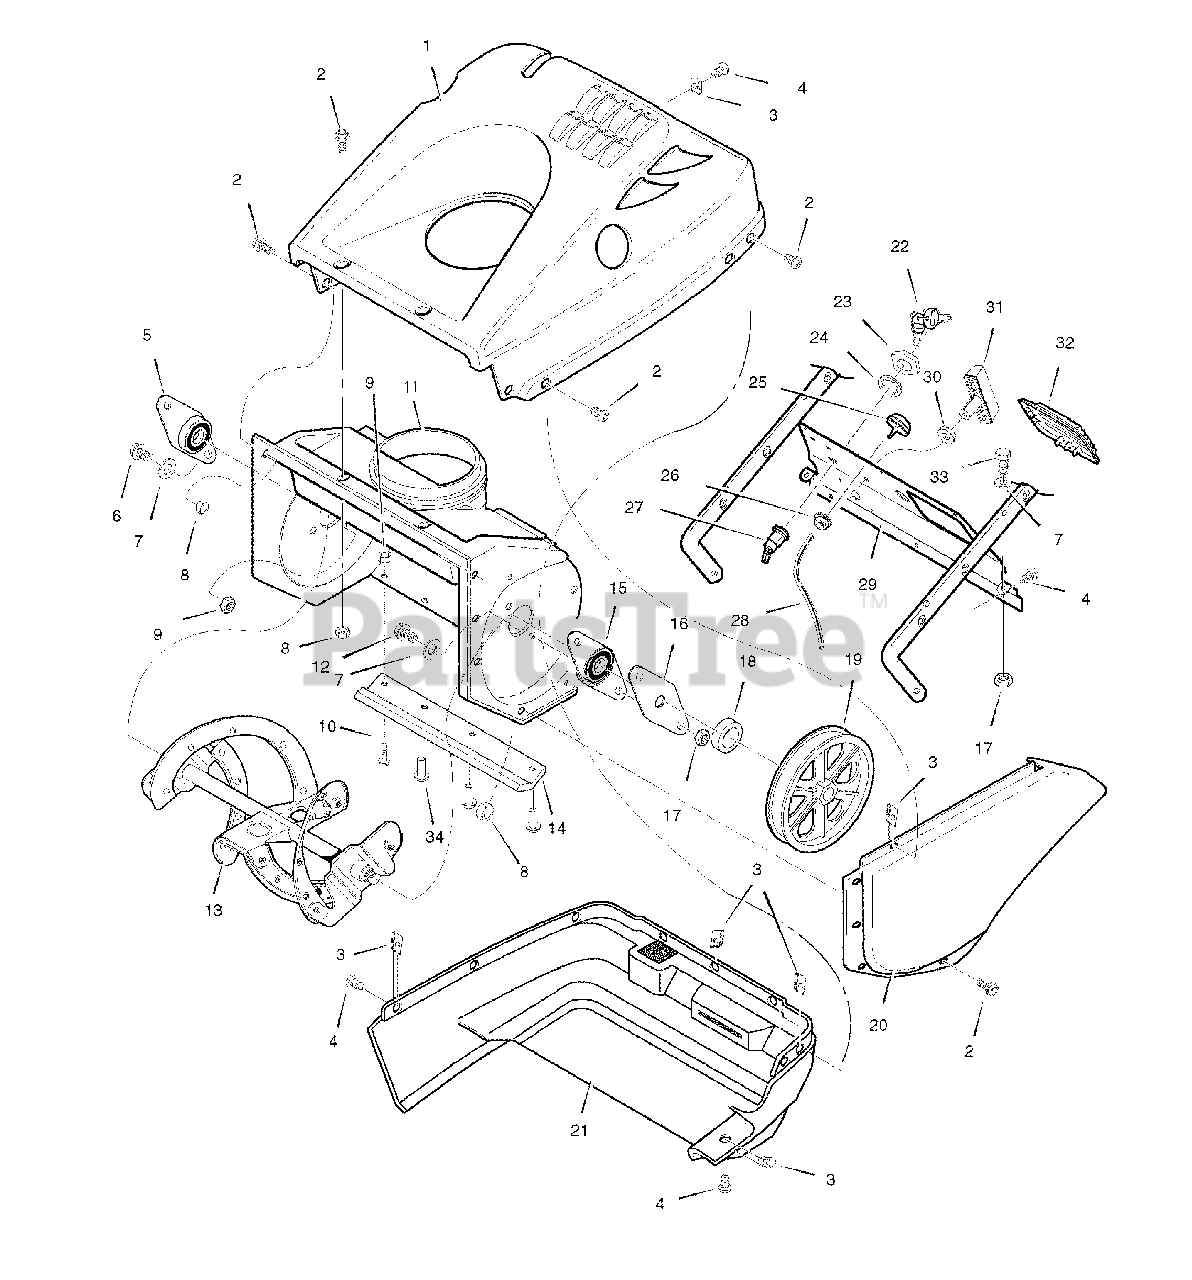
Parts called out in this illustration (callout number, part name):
1	COVER, TOP
2	SCREW, #10-24 X 0.50
3	NUT, 1/4-10 SPEED J-TYPE
4	SCREW, 1/4-14 X 0.75
5	BEARING, FLANGE
6	SCREW, 1/4-20 X 1.00
7	WASHER, FLAT, .281 X .63 X .065
8	NUT, #10-24 HEX CONTROL LOCK
9	NUT, 1/4-20 HEX CONTROL LOCK
10	SCREW, 1/4-20 X 0.75
11	AUGER HOUSING ASSEMBLY
12	SCREW, 1/4-20 X 0.63
13	AUGER ASSEMBLY, COMPLETE
14	BLADE, SCRAPER
15	PLATE & BEARING ASSY
16	PLATE, RETAINER BEARING
17	NUT, 1/4-20 HEX CONTROL LOCK
18	SPACER, SLEEVE
20	COVER, BELT
21	COVER, BOTTOM
23	NUT, 5/8-32
24	WASHER, .640 X 1.1 X .05
25	PRIMER, CARBURETOR
26	NUT, 1/-20 HEX KEPS
27	SWITCH, IGNITION 45 DEGREE
28	HOSE, PRIMER 9.5"
29	PANEL, CONTROL
30	GROMMET & WASHER, ROPE
31	GRIP, STARTER ROPE
32	PANEL, ACCESS
33	SCREW, 1/4-20 X 1.25
34	RIVET, OFFSET, .25 X .61
